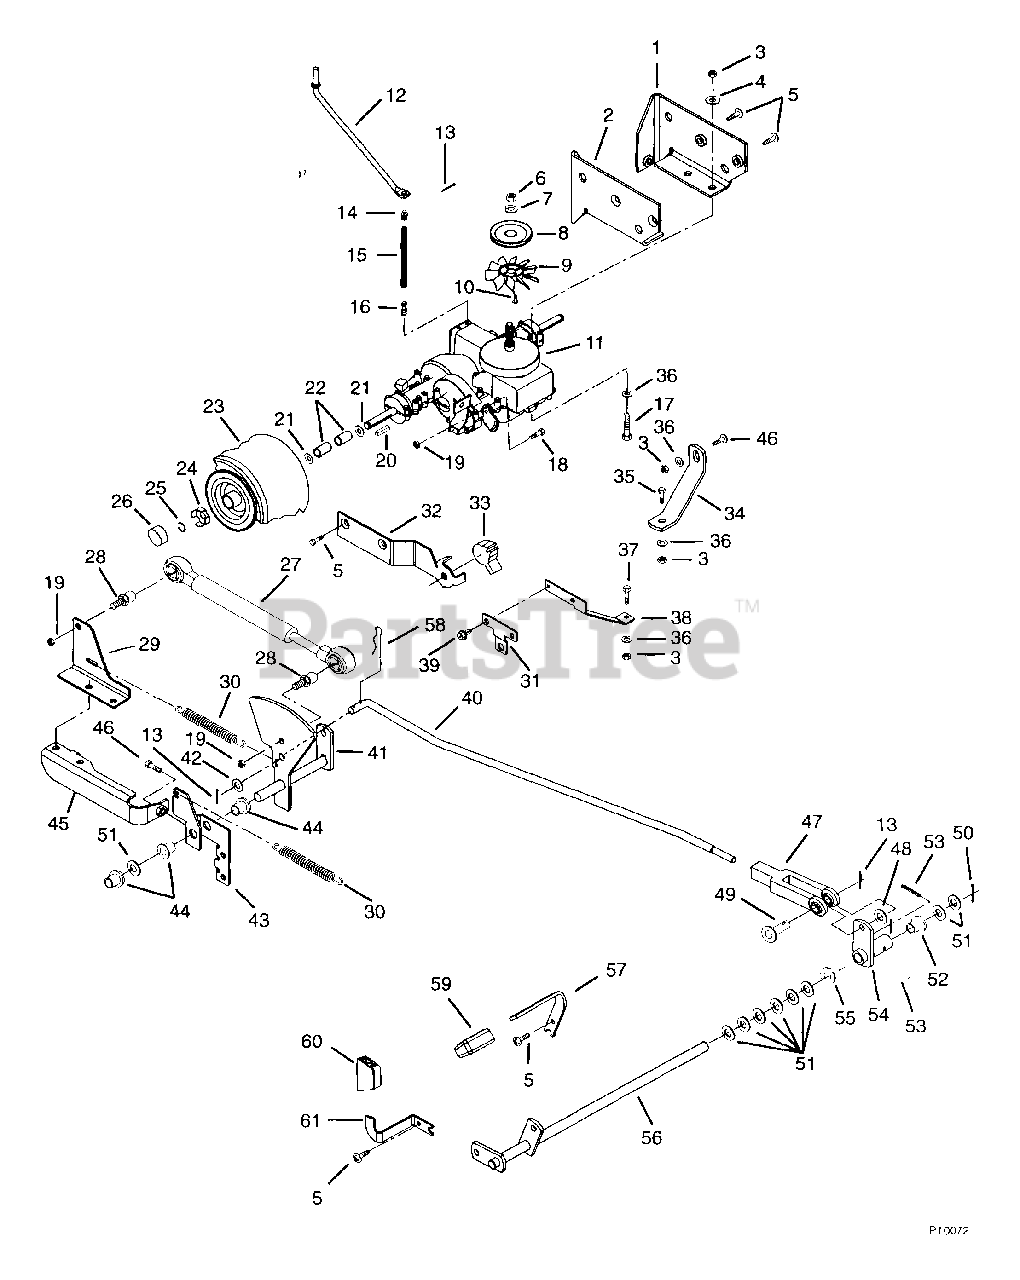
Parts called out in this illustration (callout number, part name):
1	MOUNT - TRANS. LH
2	MOUNT - TRANS. RH
3	NUT-LK-TOP .312-18 GR C PL
4	WSHR-FL-STL .328X.875X.062 PL
5	SCR-TAP .375-16X.75 HWH PL TR
6	NUT-JAM .50-20 PL
7	WSHR-LK .50 REG.
8	SHEAVE - TRANSAXLE
10	SCR-TAP 10-32X.62 HWH PL T
11	TRANSAXLE- HYDRO #325-0750
12	ROD - TRANS. DISCONNECT
13	PIN-COTR .09X.75 PL
14	CAP-VENT .50
15	HOSE- VENT .50ID X 7.50LONG
16	FTG-STR .50 O-RING
17	BLT-HEX .31-18X2.50 PL GR5
18	BLT-HEX .31-18X.75 PL GR2
19	NUT-LK .312-18 GR A PL
20	KEY-SQ .188X2.0X.188 SAE 8630
21	WSHR-FL-STL .755X1.375X.062 PL
22	BSHG-SLV .750X1.125X1.062
23	T/WHL ASSY 20X8.00-8
23	RIM
23	TIRE 20X10-8 2P TS TL
24	SPINDLE CUP
25	RG-RTNG-EXT .750X.050
26	HUB CAP
27	DAMPER - HYDRAULIC
28	STUD- BALL
29	ANCHOR - SPRING - TOP
30	SG-TENS .085X.60X5.13 WLD8.3
31	SUPPORT - SHIFT ARM
32	MOUNT - MAGNET
34	STRAP - TORQUE L.H.
35	BLT-HEX .31-18X1.50 PL GR5
36	WSHR-FL-STL.344X.688X.065PL
37	BLT-HEX .31-18X2.25 PL GR5
38	STRAP - TORQUE RH
39	SCR-TAP .312-18X.50 HWH TR BL
40	ROD - SHIFT
41	ARM - SHIFT
42	WSHR-FL-STL.406X.812X.065PL
43	PIVOT - REVERSE
44	BSHG-FLG .508X.645X.459X.75 NY
45	ANCHOR - SPRING - BOTTOM
46	BLT-HEX .31-18X.75 PL GR5
47	YOKE, .312-24 X 2.25
48	WSHR-FL-STL .390X.750X.125 PL
49	PIN-CLEV .312X.822 HDND PL
50	PIN-COTR .12X1.0 PL
51	WSHR-FL-STL .520X.827X.062 YZ
52	BSHG-FLG .515X.750X.745X1.00NY
53	PIN-GRV .188X1.25 TP A
54	ARM & HUB
55	BSHG-FLG .502X1X.750
56	SHAFT - PEDAL
57	PEDAL - FORWARD
58	PIN-HAIR INT .08X.18X1.18
59	COVER - PEDAL - FORWARD
60	COVER - PEDAL - REVERSE
61	PEDAL - REVERSE
